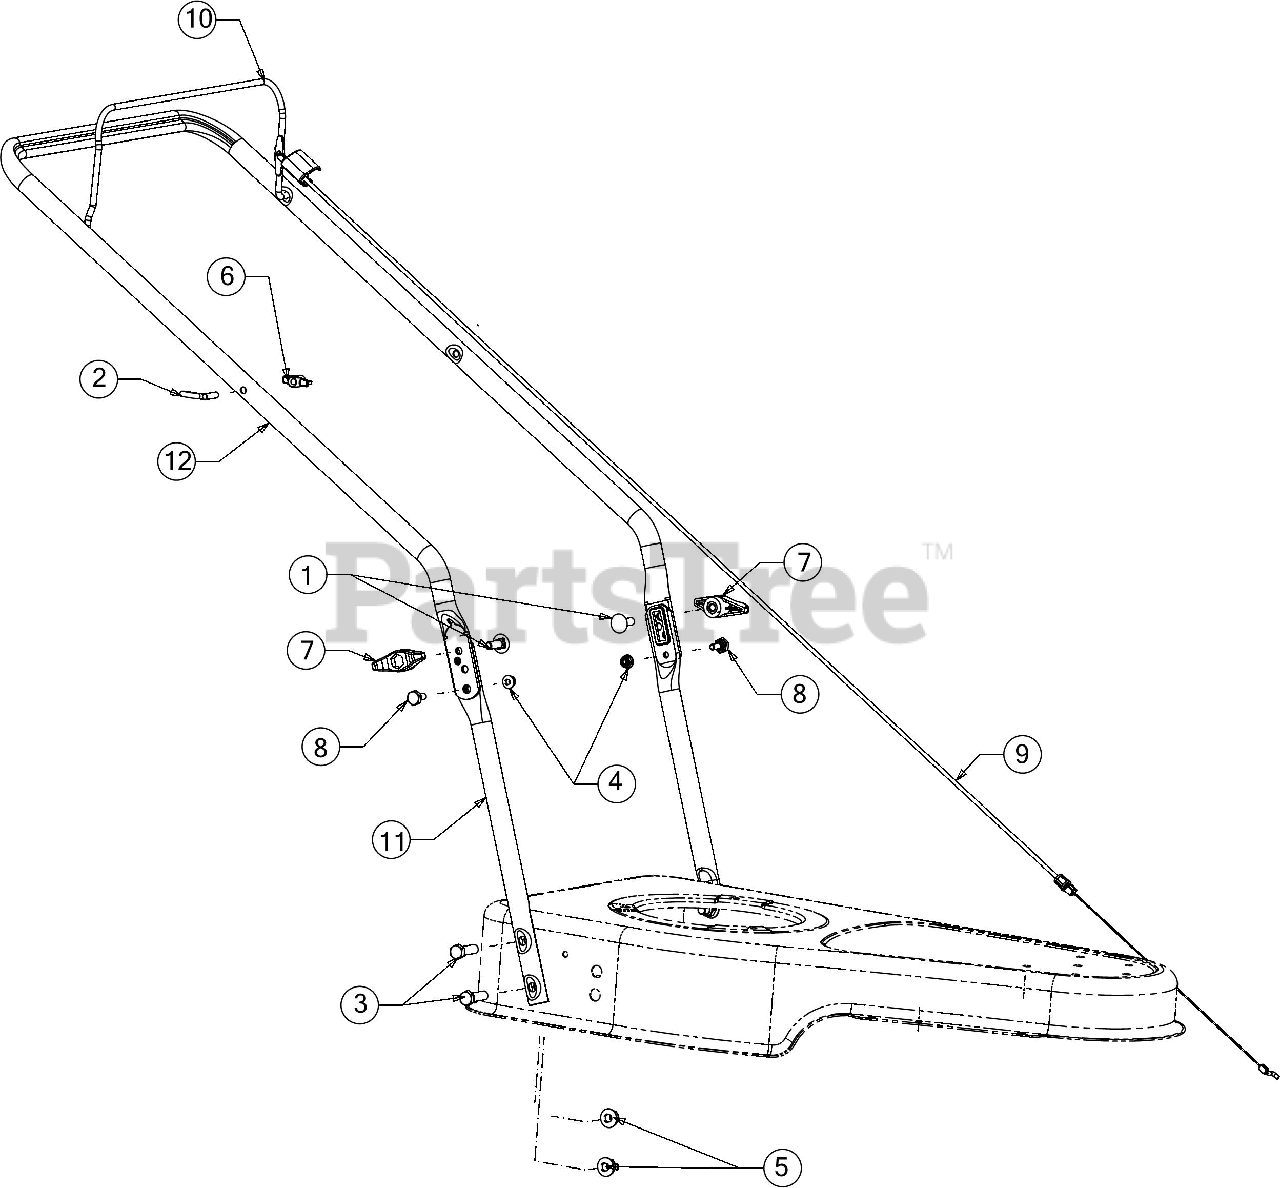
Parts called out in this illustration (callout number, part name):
1	SCREW 5/16-18 X 1.00 GR5
2	EYEBOLT 1/4-20
3	SCREW 3/8-16 X 1.25 GR5
4	FLANGE LOCK NUT
6	HANDLE KNOB
7	WING KNOB 5/16-18
8	SHOULDER SCREW
9	CONTROL CABLE 40"
10	OPERATOR BAIL
11	LOWER HANDLE (ADJUSTABLE)
12	UPPER HANDLE (ADJUSTABLE)
